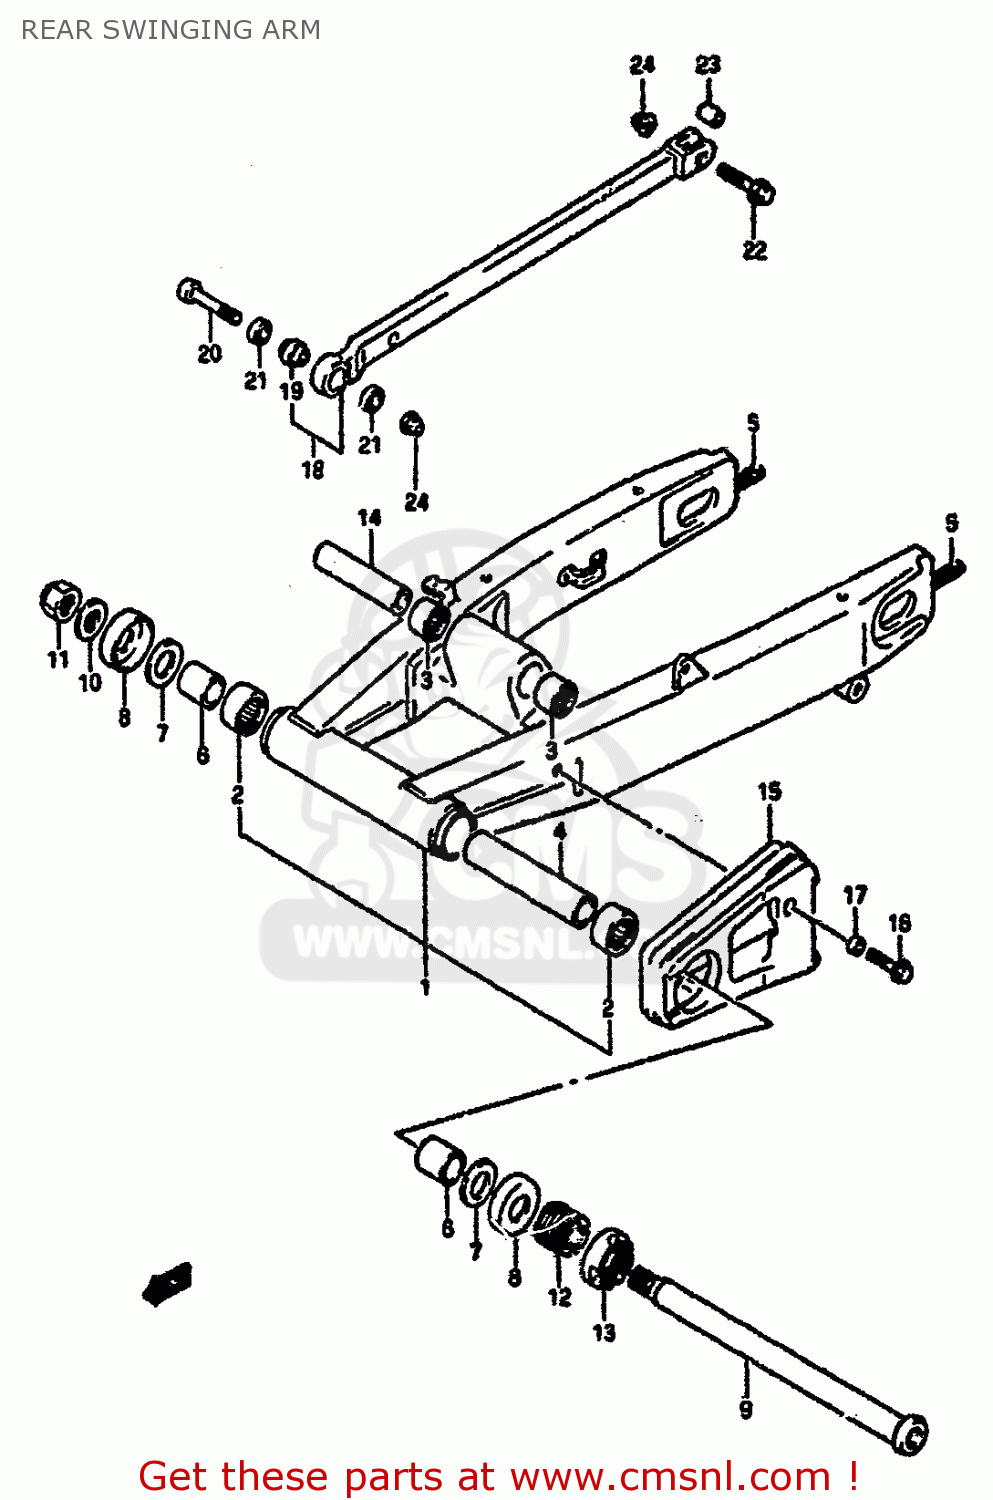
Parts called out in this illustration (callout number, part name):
1	SWING ARM ASSEMBLY,REAR
2	BEARING(25X33X30)
3	BEARING(20X27X23.5)
4	SPACER,RR SWGARM PIVOT CTR
5	STUD,CHAIN ADJUSTER BOLT
6	SPACER,RR SWGARM PIVOT BERRING
7	WASHER
8	DUST SEAL,RR SWGARM PIVOT
9	SHAFT,REAR SWING ARM PIVOT
10	WASHER
11	NUT
12	BOLT,RR SWGARM PIVOT
13	NUT,REAR SWING ARM PIVOT
14	SPACER,RR CUSHION ROD
15	BUFFER,CHAIN TOUCH DEFENSE
16	BOLT 6X20,WITH PLAIN WASHER
17	SPACER
18	TORQUE LINK SET,REAR
19	SPHERICAL BEARING,TORQUE
20	BOLT(8X48)
21	22
22	BOLT(8X38)
23	SPACER,RR TORQUE LINK RR
24	NUT
